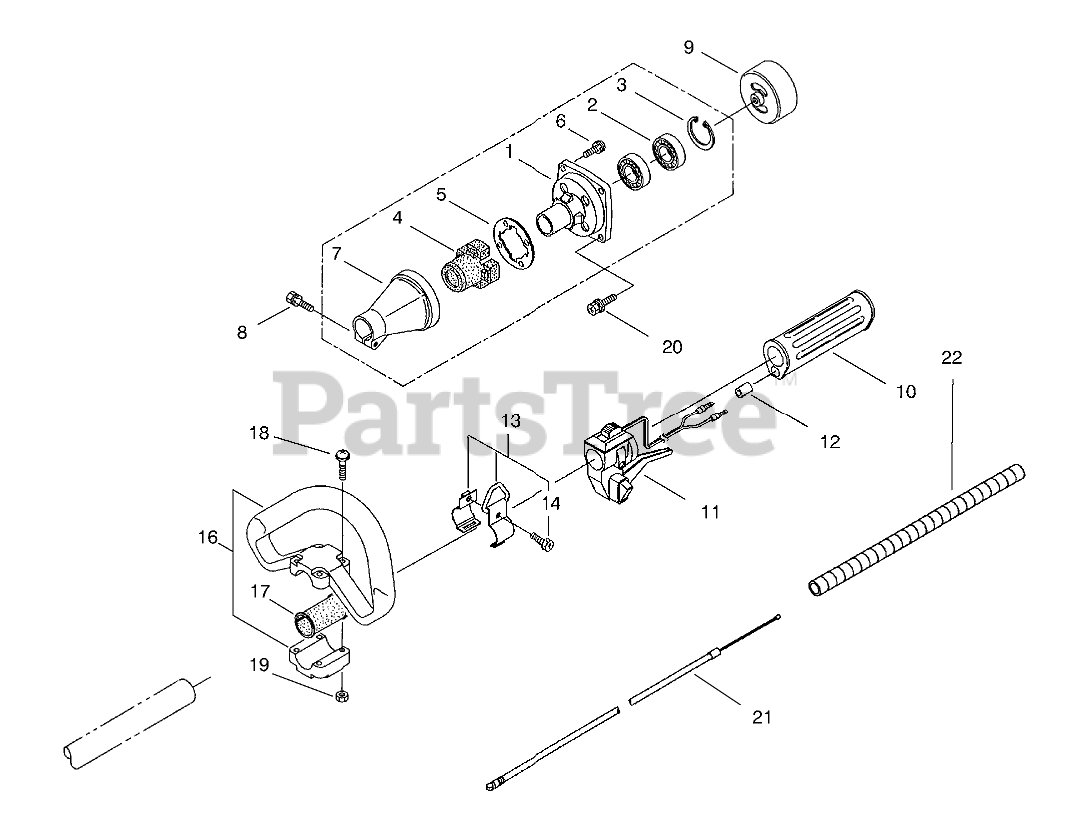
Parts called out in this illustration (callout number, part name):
1	CASE - BEARING
2	BEARING
3	RING - SNAP
4	BUFFER
5	WASHER
6	SCREW
7	ADAPTER-DRIVESHAFT TUBE
9	DRUM - CLUTCH
10	GRIP - SHAFT
11	TRIGGER - THROTTLE
12	GUIDE - OUTER
13	Hanging Bracket Assembly (Incl. Ref. #14)
16	HANDLE - LOOP
17	PACKING
18	SCREW
19	NUT M5
21	CABLE - THROTTLE
22	TUBE - PLASTIC
